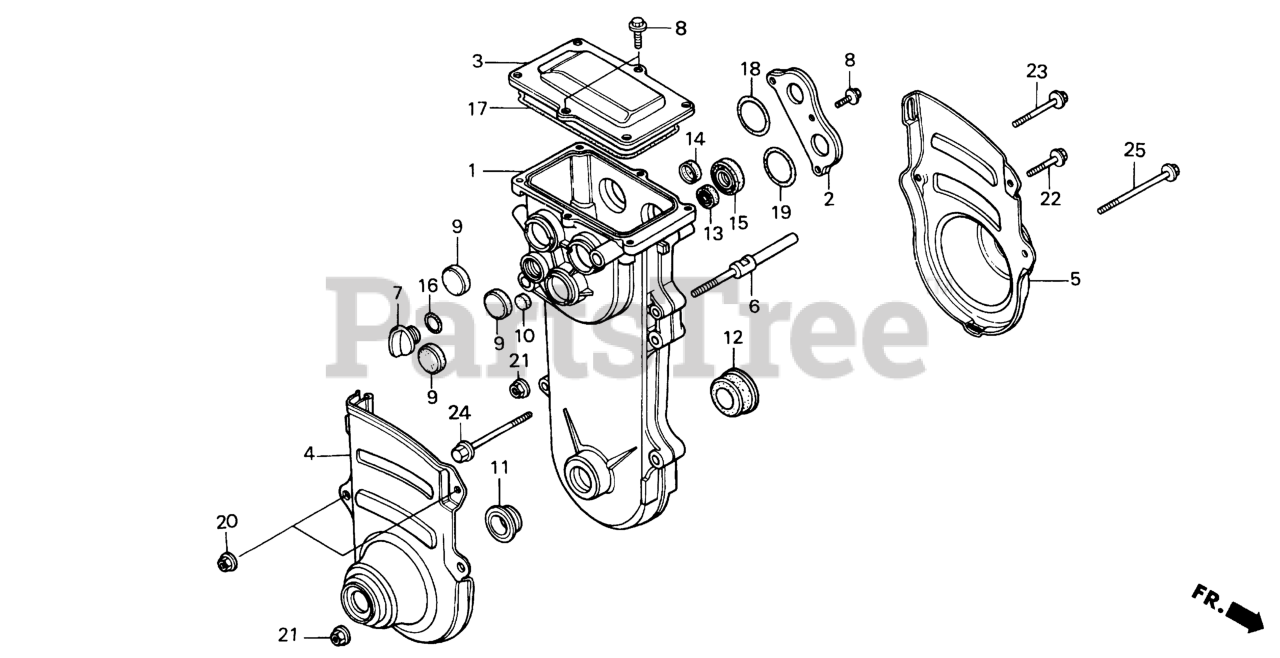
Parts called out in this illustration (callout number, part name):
1	CASE, TRANSMISSION
2	PLATE, BEARING HOLDER
3	COVER, TRANSMISSION CASE TOP
4	PROTECTOR, R. CASE
5	PROTECTOR, L. CASE
6	SHAFT, TENSIONER ARM
8	BOLT, FLANGE (6X12) (CT200)
9	PLUG, SEALING (28) (ARAI)
10	PLUG, SEALING (16) (ARAI)
11	SEAL, WATER (25X41X9.5) (NOK)
12	OIL SEAL (25X52X9)
13	OIL SEAL (12X22X6)
15	OIL SEAL (15X35X7) (ARAI)
16	O-RING (16MM)
17	O-RING A, TRANSMISSION CASE
18	O-RING (40.5X2.5) (ARAI)
19	O-RING (45.5X2.5) (ARAI)
20	NUT, FLANGE (6MM)
21	NUT, FLANGE (8MM)
22	BOLT, FLANGE (6X10)
23	BOLT, FLANGE (6X40)
24	BOLT, FLANGE (8X55)
25	BOLT, FLANGE (8X65)
